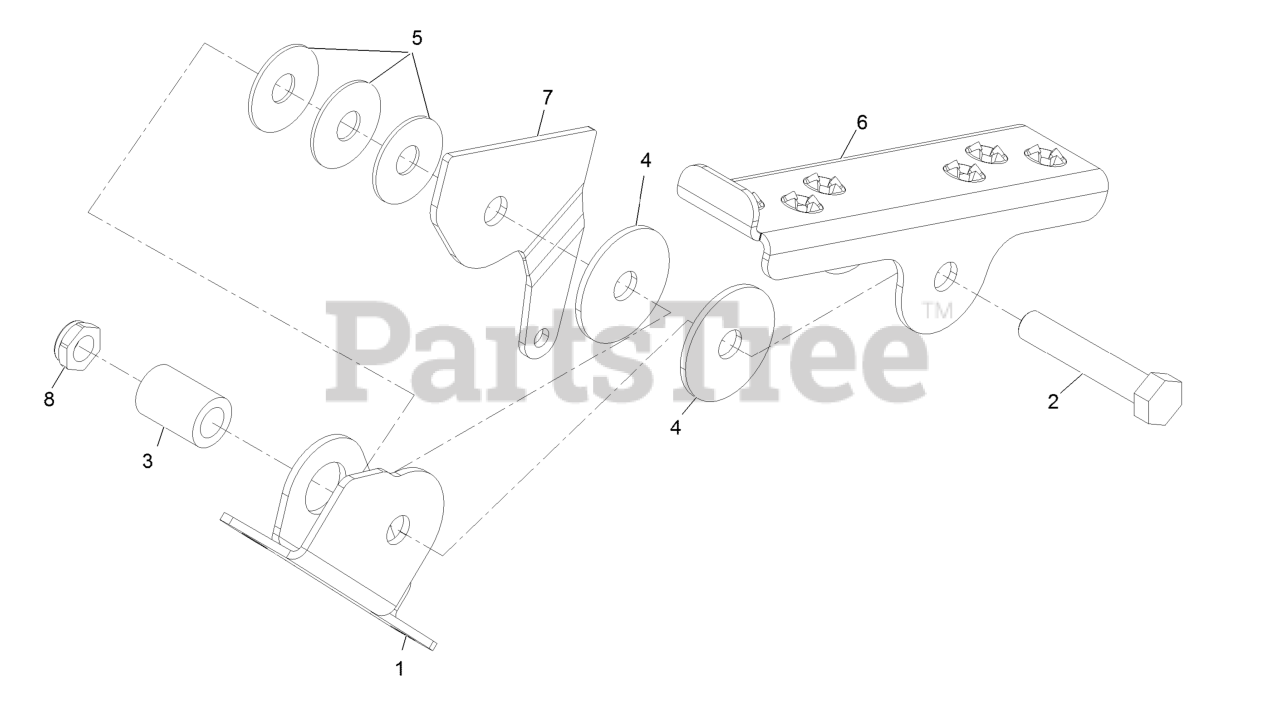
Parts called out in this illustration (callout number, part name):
1	BRACKET-PEDAL MOUNT
2	SCREW-HH
3	SPACER-ROLLER
4	DISC-FRICTION
5	WASHER-DISC, SPRING
6	CHANNEL,PEDAL LINK
7	ARM, FOOT PEDAL
8	NUT-HEX
